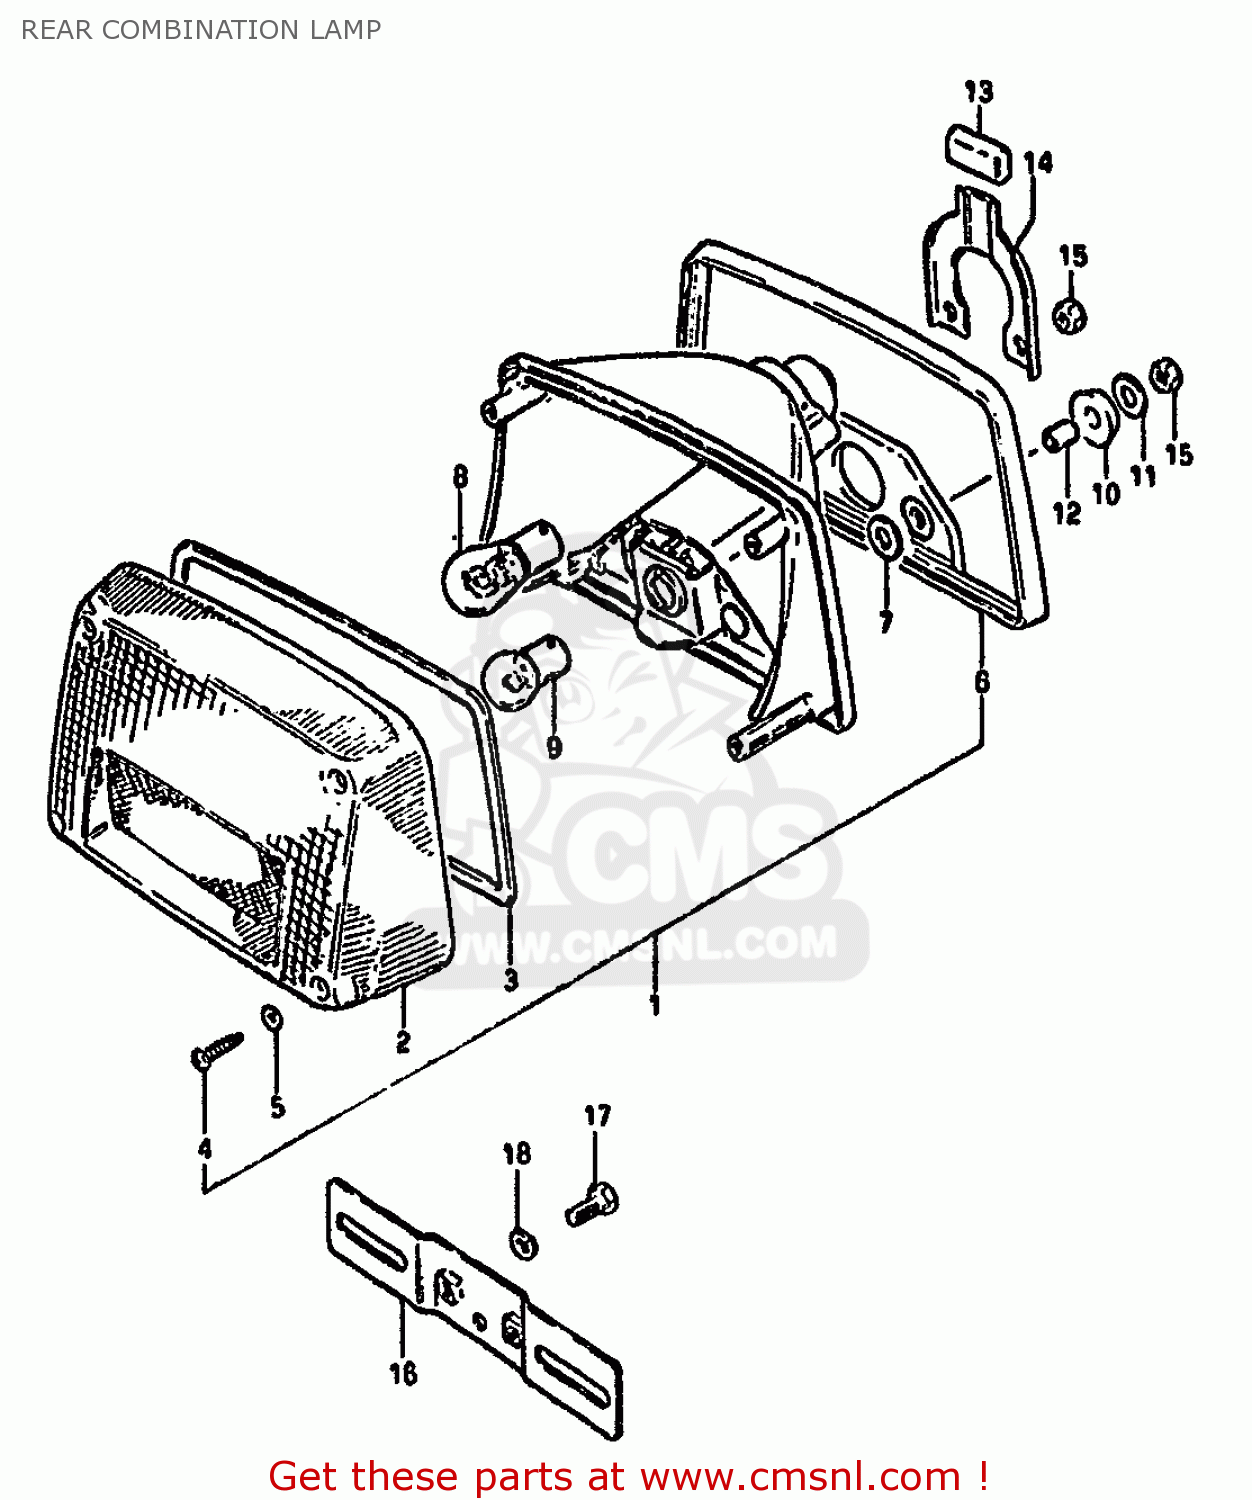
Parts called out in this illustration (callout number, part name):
1	LAMP ASSY, TAIL
2	LENS
3	GASKET (NAS)
4	SCREW,REAR COMBINATION LAMP
5	GASKET (NAS)
6	CUSHION,REAR COMBINATION LAMP
7	WASHER,REAR COMBINATION LAMP
8	BULB(12V21/5W)
9	BULB
10	CUSHION,RR COMBINATION LAMP
11	WASHER
12	SPACER (6.4X9X10.5)
13	CUSHION,REAR COMBINATION LAMP
14	PLATE
15	NUT 6MM
16	BRACKET, LICENSE PLATE
17	BOLT
18	LOCK WASHER
